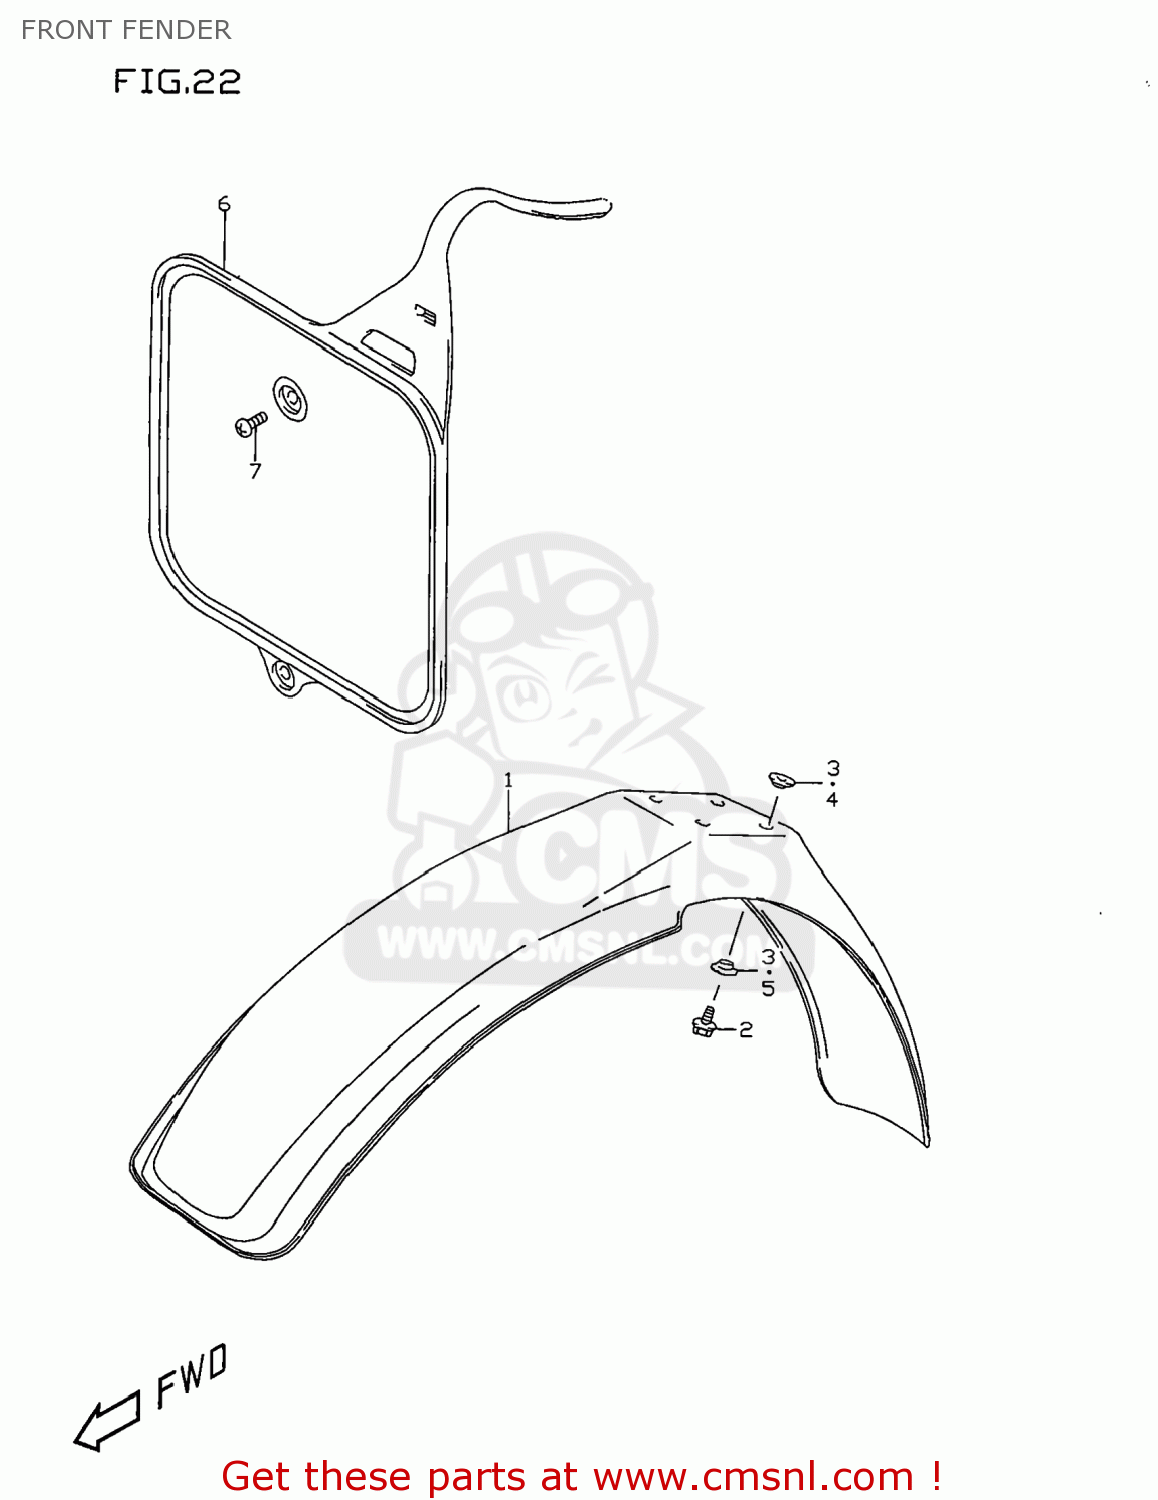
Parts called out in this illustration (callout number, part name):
1	FENDER,FRONT
2	BOLT
3	WASHER
4	WASHER
5	WASHER
6	PLATE,NUMBER FR
7	SCREW
